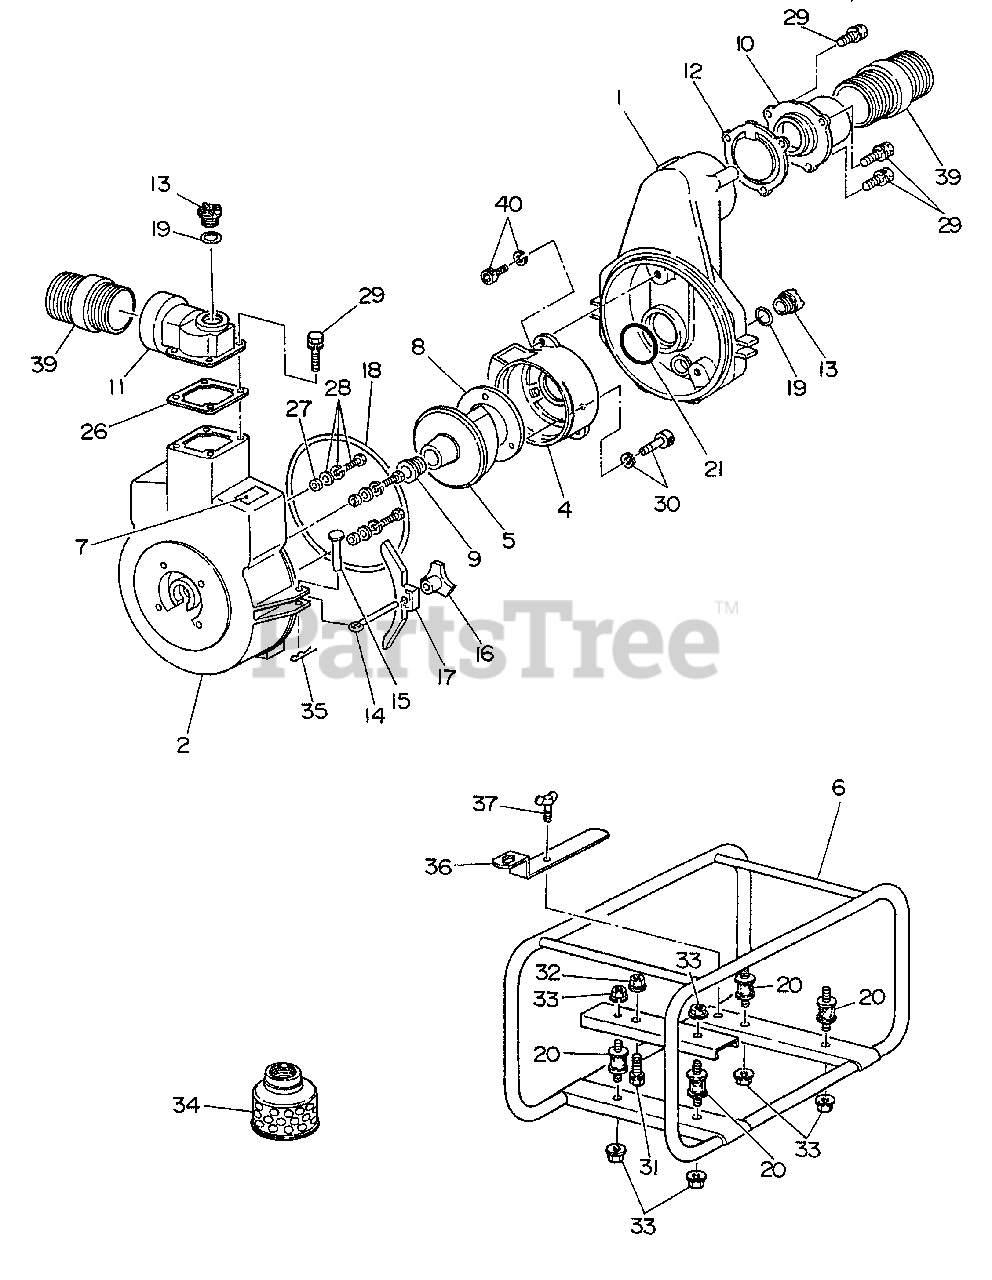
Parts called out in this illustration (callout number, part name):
1	CASING
2	COVER, CASING
4	INNER CASING
5	IMPELLER
6	FRAME
7	LABEL - PUMP
8	LINER
10	SUCTION FLANGE
11	DELIVERY FLANGE
12	VALVE, CHECK
13	PLUG
14	COVER, BOLT
15	RIVET
16	KNOB
17	HOLDER, CASING COVER
28	BOLT - 4X48
29	BOLT - 8X25
30	SCREW - 6X16
31	BOLT - 8X40
32	NUT - 8 -- FLANGE
33	NUT - 8
34	STRAINER, DEBRIS
35	PIN - SPRING
36	SUPPORT
37	THUMBSCREW
39	NIPPLE (NPT x NPT)
40	SCREW - 6X16
